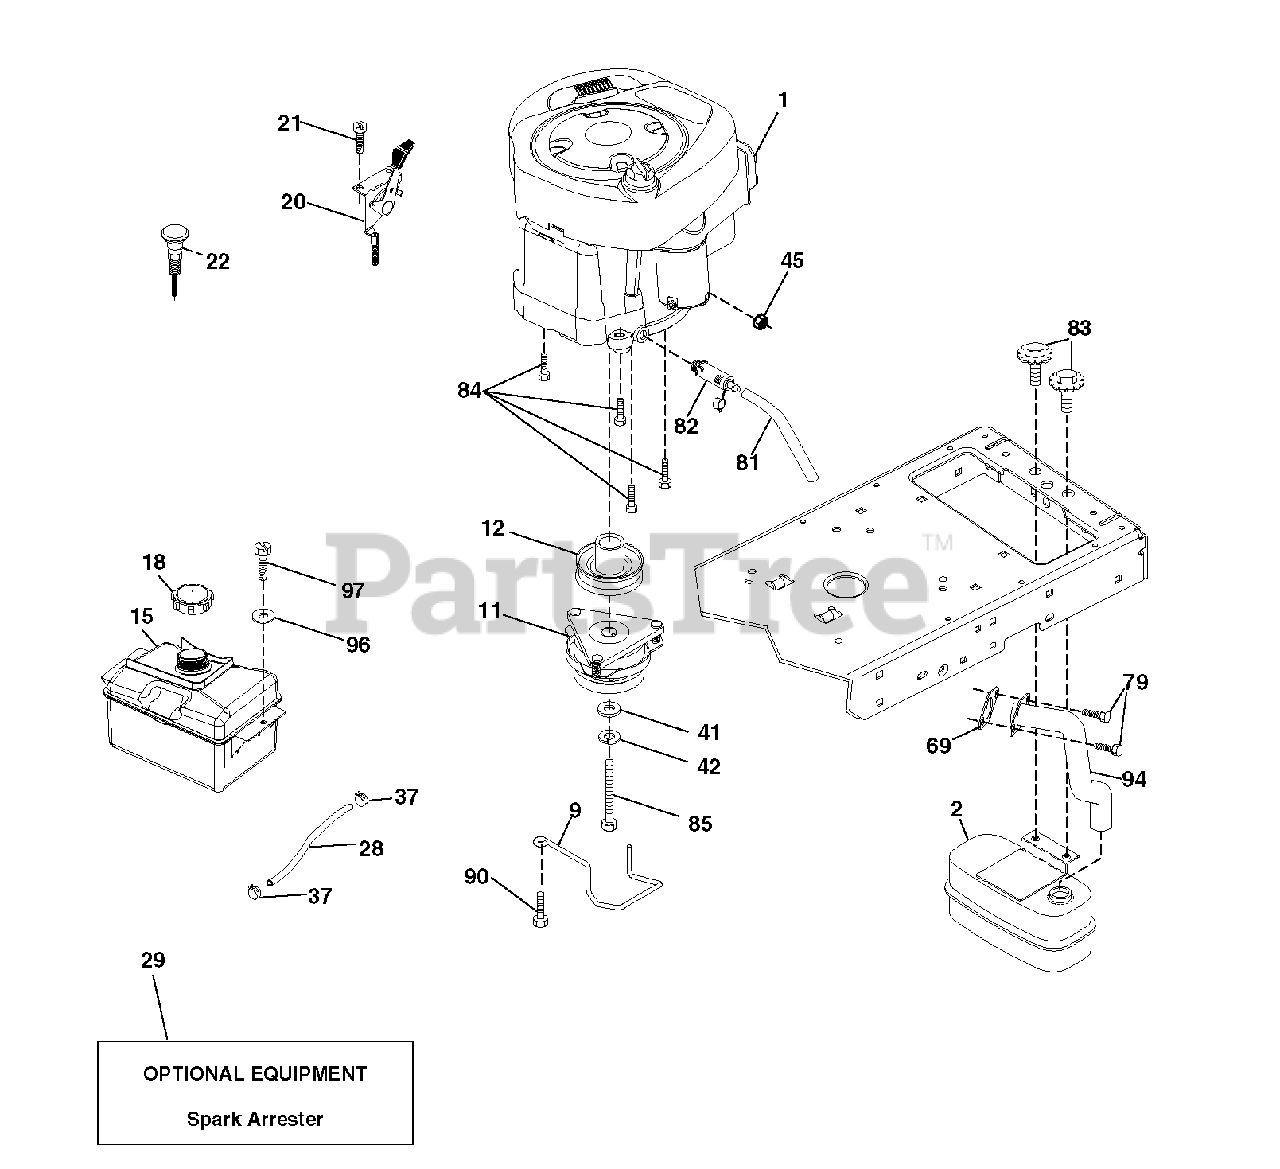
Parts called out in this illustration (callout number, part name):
2	MUFFLER.SINGLE.CYL.KOHL/B&S
9	KEEPER.BELT.ENGINE.4.2
11	CLUTCH
12	PULLEY.ENGINE.TUFFTORQ
18	FUEL CAP
20	CONTROL.TH/CK.COBRA.KO
21	SCREW.#10 X 0.750.BOS THREAD
28	LINE.FUEL.20
29	ARRESTER SPARK (OPTIONAL)
37	HOSE CLAMP
42	LOCKWASHER
45	NUT
69	REPL BY 532 27 22-93
79	SCREW.SOCKET HD.5/16-1
81	TUBE, DRAIN OIL ASM.
82	PLUG DRAIN OIL EASY
83	BOLT, 5/16-18 X 1 3/4
84	SCREW.3/8-16
85	BOLT HEX 7/16-20X4-1/4"
90	SCREW 3/8-16X1
94	EXHAUST.TUBE.B&S.
97	SCREW HEXWSHR 1/4-20X3/4
